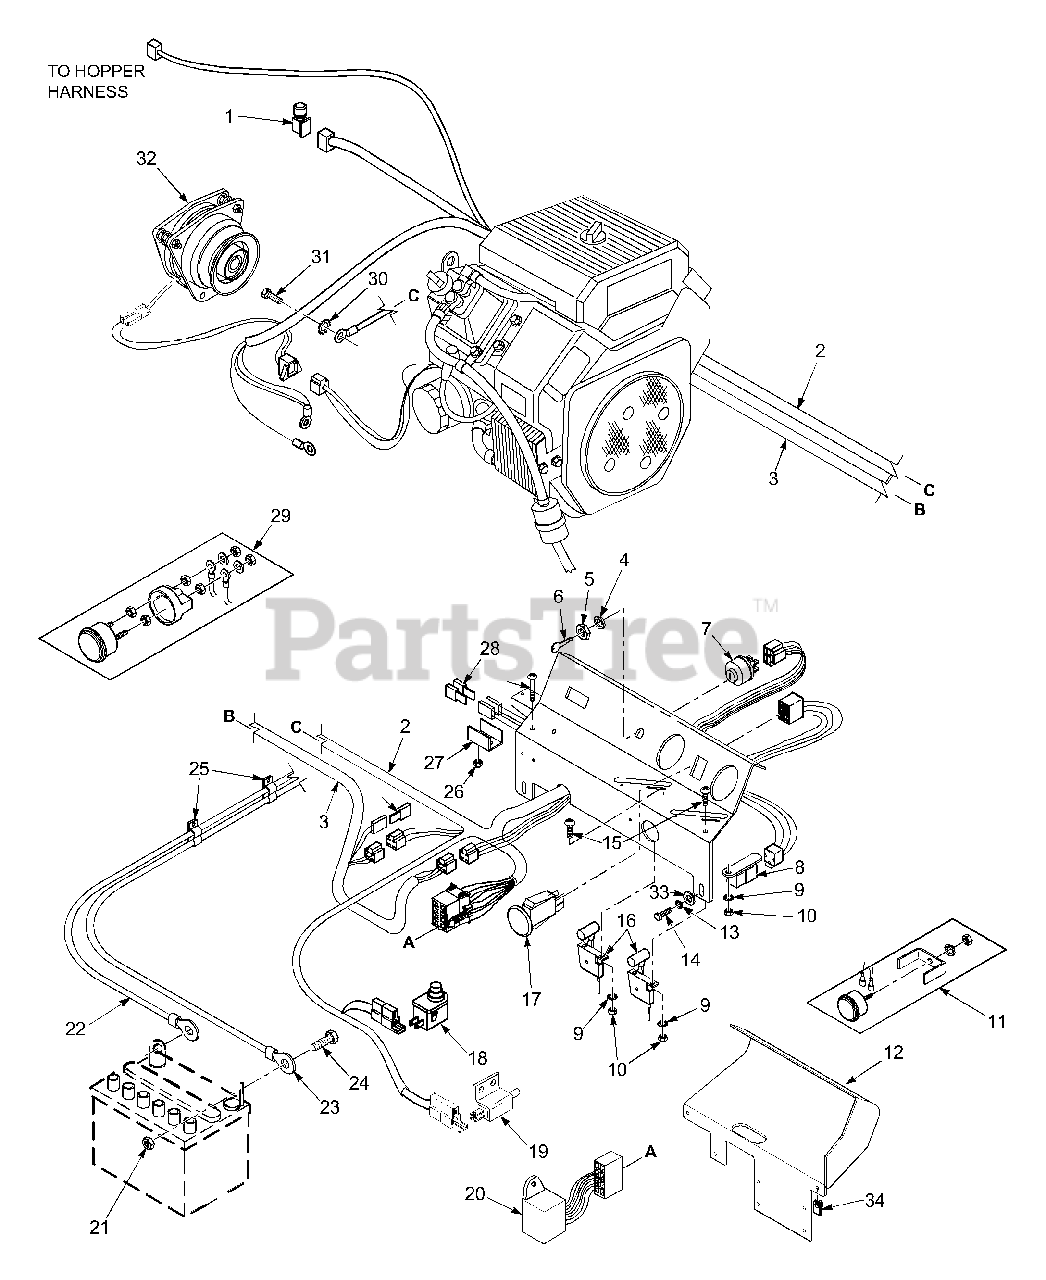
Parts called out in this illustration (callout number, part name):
1	Switch, Hopper
2	Wire Harness, SCR
3	Wire Harness, Hopper
4	Lockwasher, Internal 5/8"
5	Nut, 5/8-32 Special
6	Key & Ring
7	Keyswitch w/hardware
8	Relay
9	Lockwasher, #10 external tooth
10	Nut, #10-32 UNF
11	Hour Meter
12	Instrument Panel, Lower
13	Lockwasher, 5/16
14	Bolt, Hex Head 5/16-18 x 1"
15	Screw, #10-32 x 1/2"
16	Control Cable
17	Switch, PTO
18	Switch, Seat
19	Switch, Brake
20	Interlock Module
21	Nut, 1/4-20
22	Battery Cable, Black
23	Battery Cable, Red
24	Bolt, Hex Head 1/4-20 x 1/2"
25	Cable Clamp, Double
26	Nut, Elastic Stop #10
27	Bracket, Fuse Holder
28	Fuse, 20 Amp
29	Ammeter
30	Lockwasher, 3/8"
31	Bolt, Hex Head
32	Electric Clutch, Ogura
33	Flatwasher, 5/16-.375 x .875 x .083
34	U-Nut, 5/16-18
